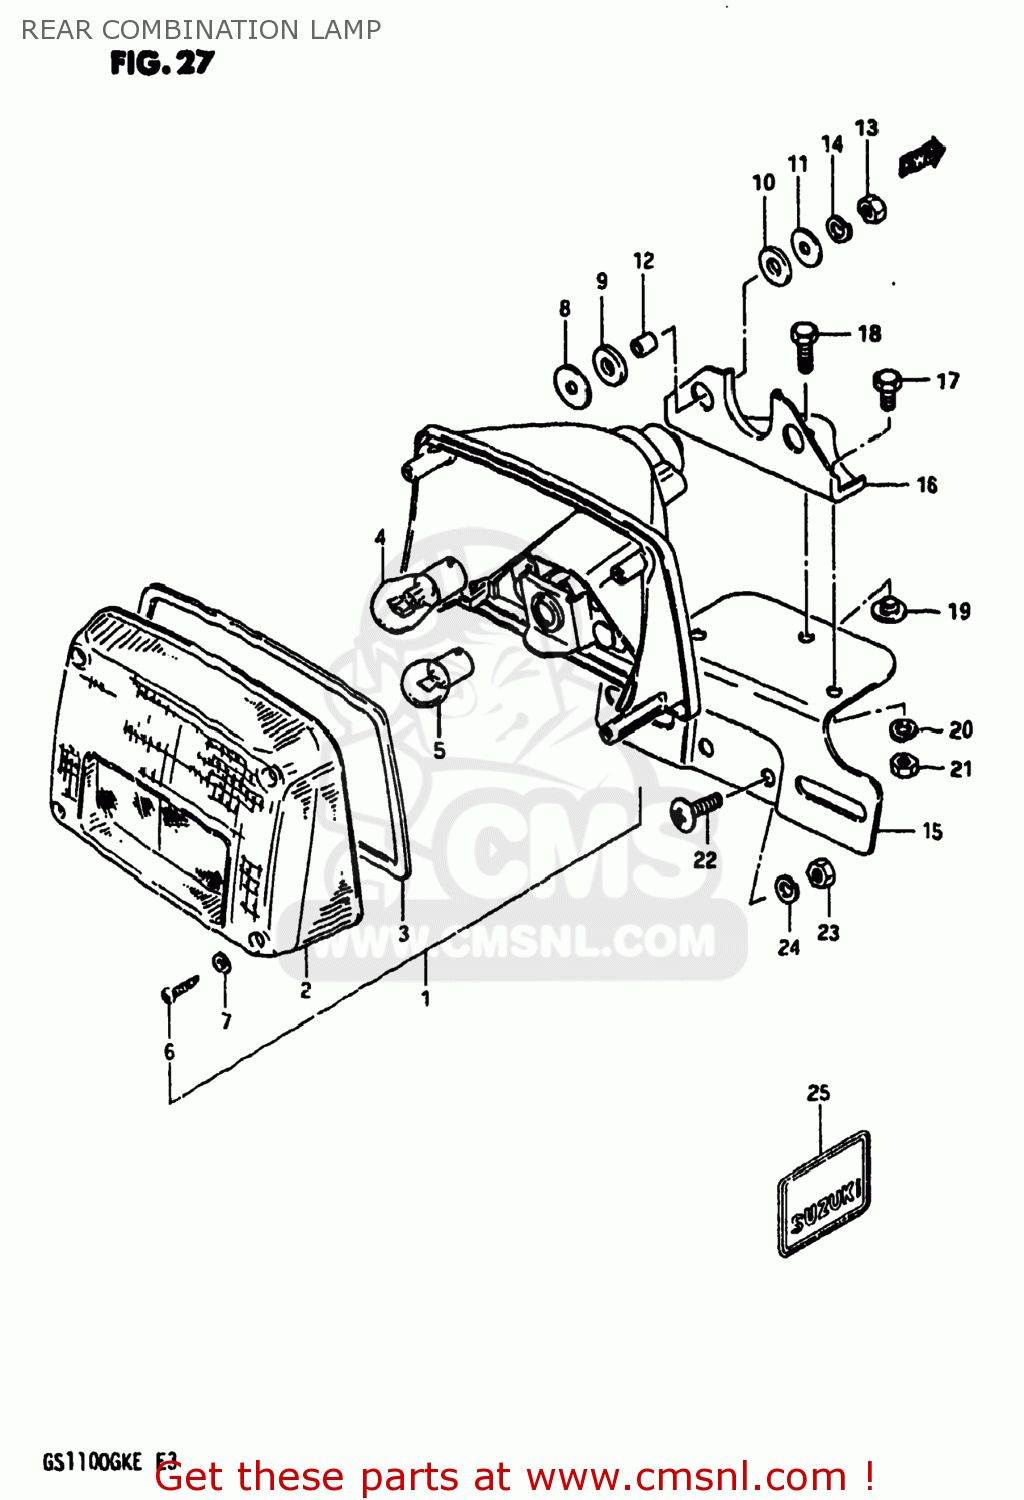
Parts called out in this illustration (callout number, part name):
1	LAMP ASSEMBLY,REAR COMBINATION
2	LENS
3	GASKET (NAS)
4	BULB(12V23W)
5	BULB
6	SCREW,REAR COMBINATION LAMP
7	GASKET (NAS)
8	WASHER
9	CUSHION
10	CUSHION
11	WASHER(6,5X22X1.6)
12	SPACER(6.1X9X7.5)
13	NUT
14	WASHER,LOCK
15	PLATE,REAR LICENSE
16	BRACKET,REAR COMBINATION LAMP
17	BOLT
18	BOLT, UPPER
19	WASHER
20	WASHER,LOCK
21	NUT
22	SCREW
23	NUT
24	WASHER,LOCK
25	EMBLEM,SEAT TAIL COVER
